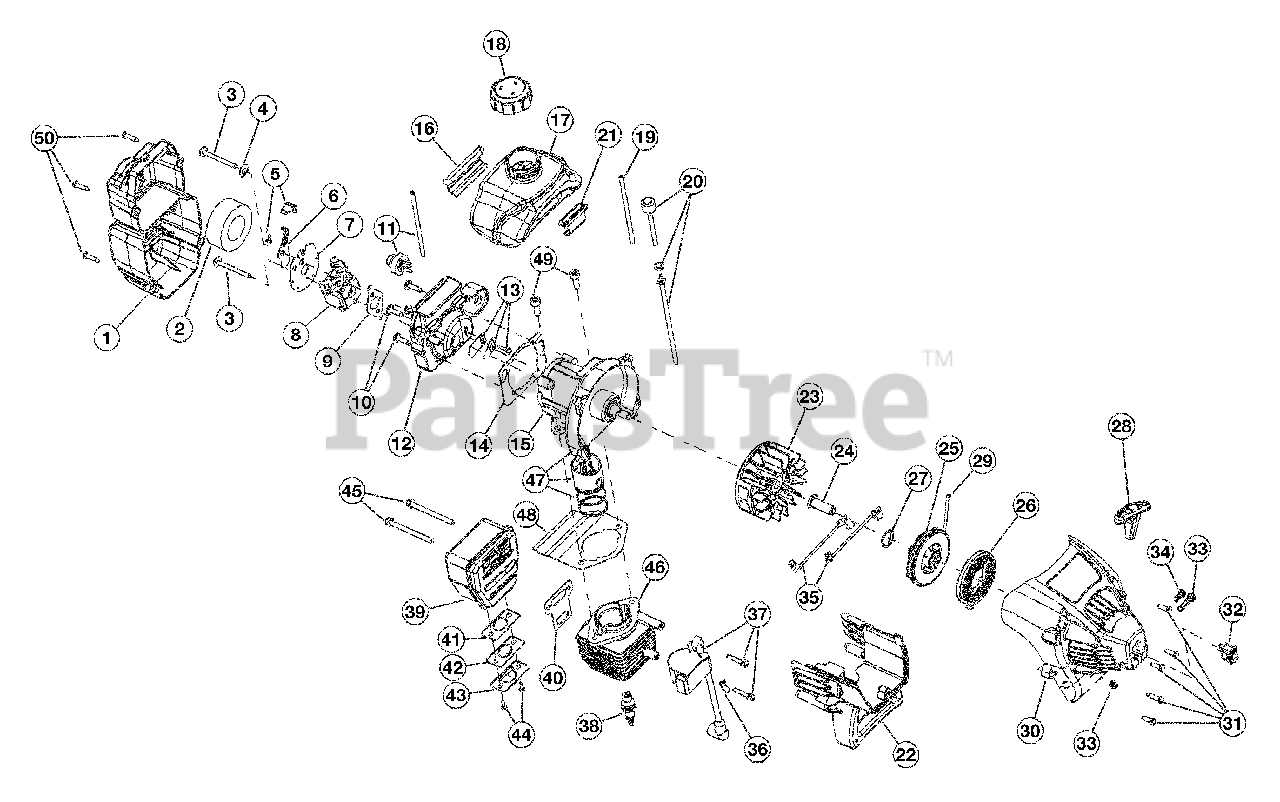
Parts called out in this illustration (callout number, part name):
1	Air Cleaner Cover Assembly
2	Air Cleaner Filter
3	Carburetor Mounting Screws
4	Wavy Washer
5	Choke Knob and Screw
6	Choke Lever Assembly
7	Choke Plate Assembly
8	Carburetor Assembly
9	Carburetor Gasket
10	Carb Mount Screw
11	Primer Assembly
12	Carb Mount Assembly
13	Reed Assembly
14	Carburetor Mount Gasket
15	Crankcase Service Assembly
16	Rear Mounting Pad
17	Fuel Tank Assembly
18	Fuel Cap Assembly
19	Fuel Return Line
20	Fuel Line Assembly
21	Front Mounting Pad
22	Shroud Extension and Stand
23	Flywheel Assembly
25	Recoil Pulley
26	Recoil Spring
27	Pulley Retainer
28	Pull Handle
30	Starter Housing Assembly
31	Housing Screws
32	On/Off Switch
33	Clamping Screw & Nut
34	Anti-Rotation Screw
35	Wire Leads
36	Ground Tab
37	Module Assembly
38	Spark Plug
39	Muffler Assembly
40	Exhaust Gasket
41	Spark Arrestor
42	Exhaust Hood Diverter
43	Exhaust Hood
44	Screws
45	Muffler Mounting Bolt
46	Cylinder Assembly
47	Piston Assembly
48	Cylinder Gasket
49	Cylinder Bolt
50	Cover Screws
